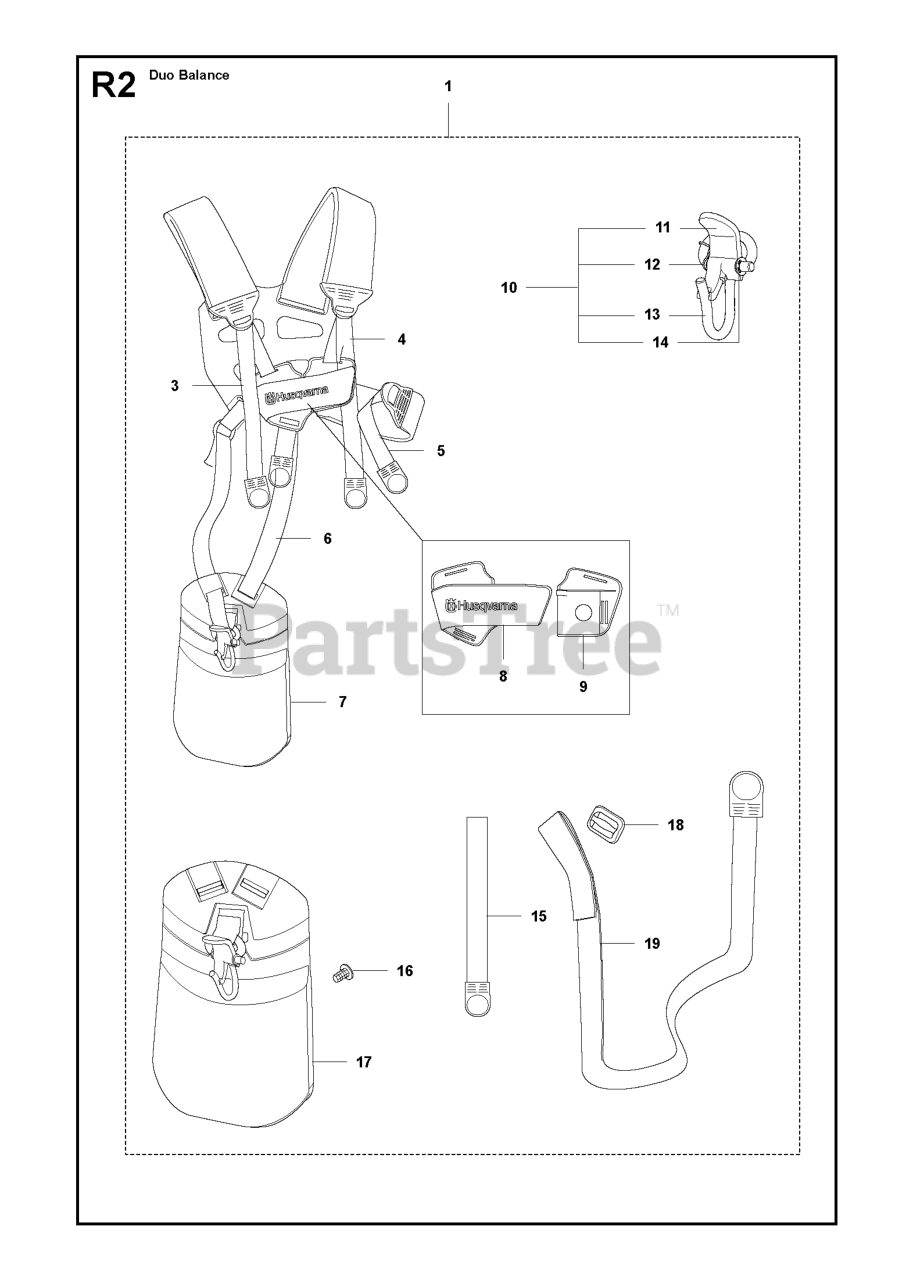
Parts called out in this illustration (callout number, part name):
1	Harness
1	Duo Balance Harness
8	FRONT PIECE
9	FRONT PIECE
10	HARNESS HOOK, COMPLETE
11	CATCH *
12	SPRING LOCKING
13	HOOK
18	RP CLIP
